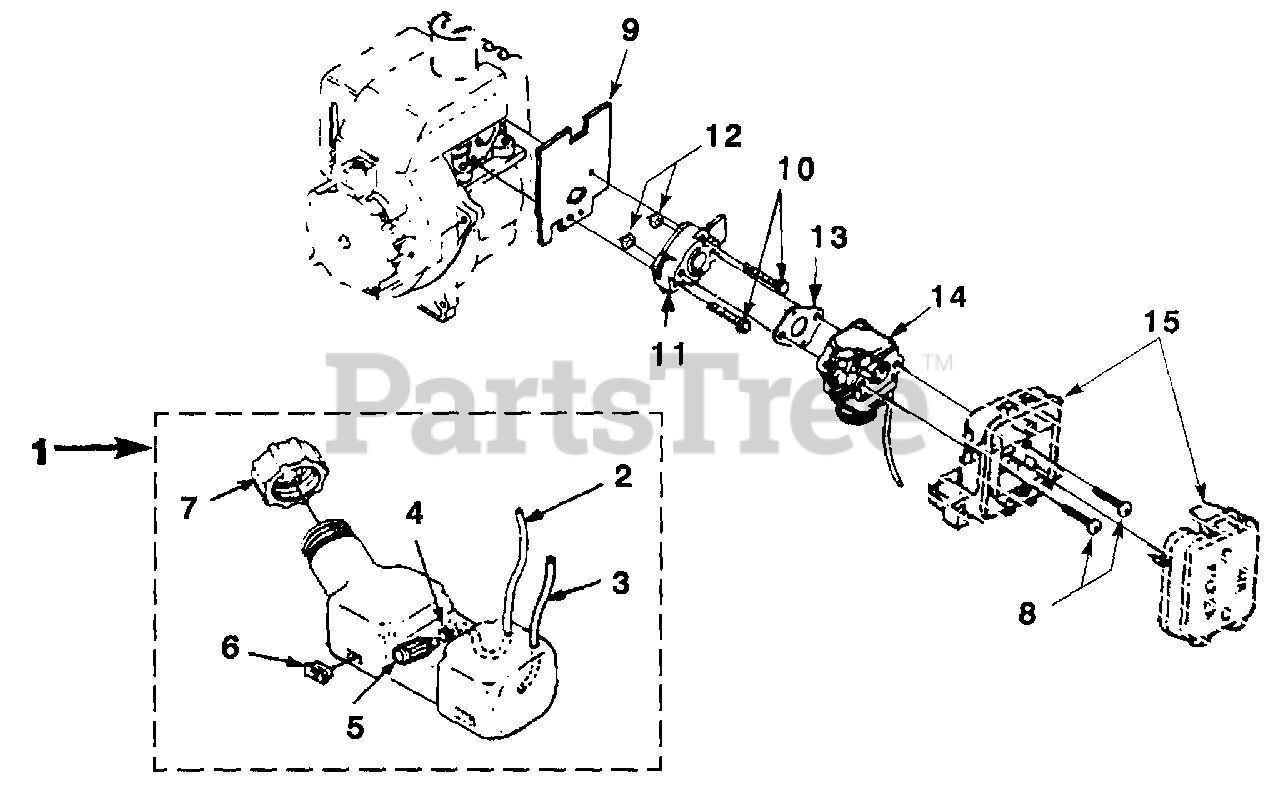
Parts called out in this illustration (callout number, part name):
1	FUEL TANK
2	TUBING-Rubber (4 1/4")
3	TUBING-Rubber (7 1/2")
4	CLAMP-Wire
5	FILTER-Fuel
6	BUMPER-Rubber
7	CAP-Fuel Tank
8	SCREW-Sems Hex Hd. (10-24 x 2 1/2")
9	GASKET-Heat Dam
10	SCREW-Sems, Torx (10-24 x 1.12")
11	HEAT DAM
12	NUT-Hex (10-24)
13	GASKET-Carburetor
14	CARBURETOR (Zama)
15	AIR FILTER
